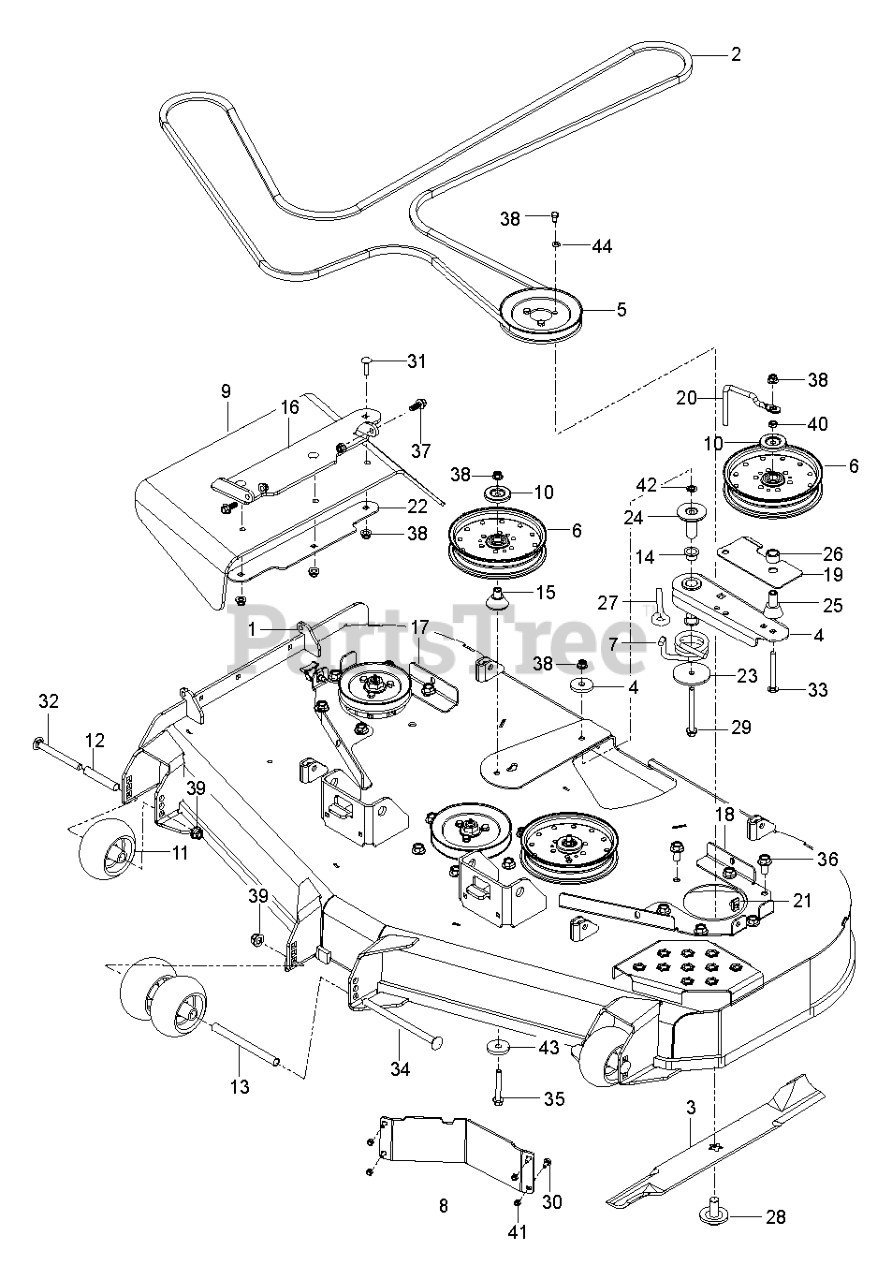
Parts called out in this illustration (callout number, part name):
1	DECK.W/DECALS.60".7GA.ORG
2	BELT 5V 176.00
3	BLADE 21" MID LIFT WITH HOLES
4	ARM.PNT.WLD.TENSIONR.IDLER.BLK
5	PULLEY - 6.57
6	PULLEY - IDLER 7"
7	SPRING.TORSION.DECK.IDLER.TMSN
8	BAFFLE, DIVERTER 54"/60" LH
9	CHUTE.DISCHARGE
10	DUST SHIELD
11	ROLLER, GAUGE .635 BORN
12	TUBE, ROLLER AXLE
13	TUBE, ROLLER AXLE LONG
14	BEARING, FLANGE
15	BEARING, IDLER ARM
16	BRACKET.CHUTE.ORG
17	BRACKET PULLEY COVER MOUNT LH
18	BRACKET PULLEY COVER MOUNT RH
19	BELT.GUIDE.LOWER.PLATE.MS431
20	KEEPER KEEPER., BELT
21	U-CLIP 5/16-18 NUT RETAINER
22	PLATE.BACKING.DISCHARGE.CHT.BK
23	PLATE.SPRING.RETAINER
24	SHAFT.MOUNT.ARM.IDLER
25	SPACER
26	SPACER.PULLEY.INTERMEDIATE
27	EYE BOLT, 3/8 X 4"
28	BLADE BOLT/WASHER
29	HHFS 3/8-16 X 4 GR5 ZD
30	1/4-20X3/4 CARR BLT
31	BOLT.3/8-14X1.25
32	RHSNB 1/2-13 X 4.75 GR5 ZD
33	BOLT.RDHD SQNK 3/8-16 X 3-1/2
34	RHSNB 1/2-13 X 8 GR5 ZD
35	HHFS 3/8-16 X 2-3/4 GR5 ZD
36	HHFS 1/2-13 X 1 GR5 ZD
37	HHFS 3/8-16 X 1 GRD 5 ZD
38	NUT 3/8-16 HEX FLG NYLOC ZD
39	NUT, 1/2-13 HEX FLG NYLOC ZD
40	NUT 3/8-16 HEX JAM
41	NUT.1/4-20.HEX.NYLOC.ZD
42	NUT 3/8 PALNUT RTNG BLK PHOS
43	SPINDLE WASHER
44	WASH 5/16 DISC SPRING ZD
